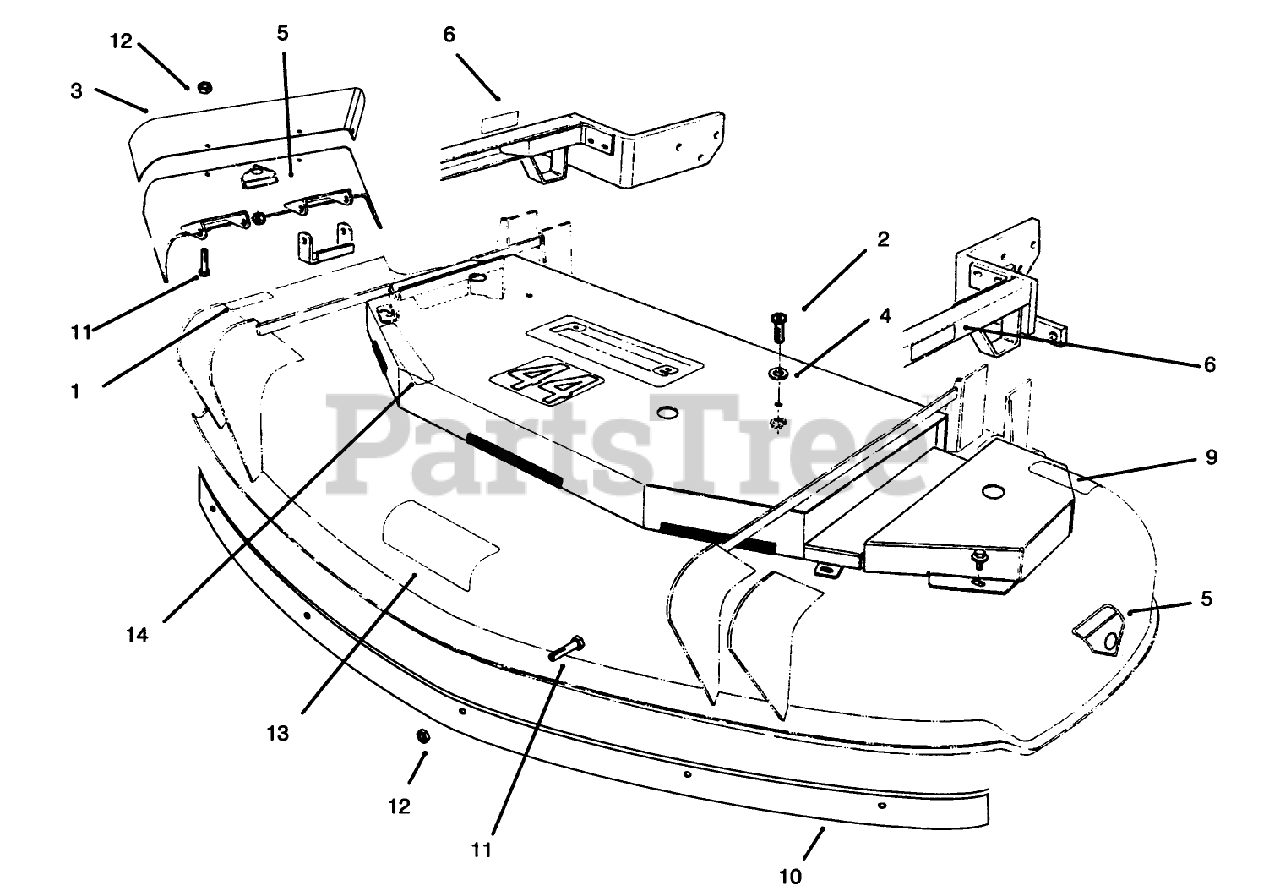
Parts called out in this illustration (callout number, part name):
1	DECAL-DANGER
2	SCREW-HH
3	Guard-Deflector
4	WASHER-FLAT
5	DECAL-DANGER
6	DECAL-HOC
9	DECAL-TORQUE, BLADE BOLT
10	Baffle-Front
11	SCREW-HH
12	NUT-LOCK, NI
13	DECAL - WARNING
14	DECAL-DANGER
